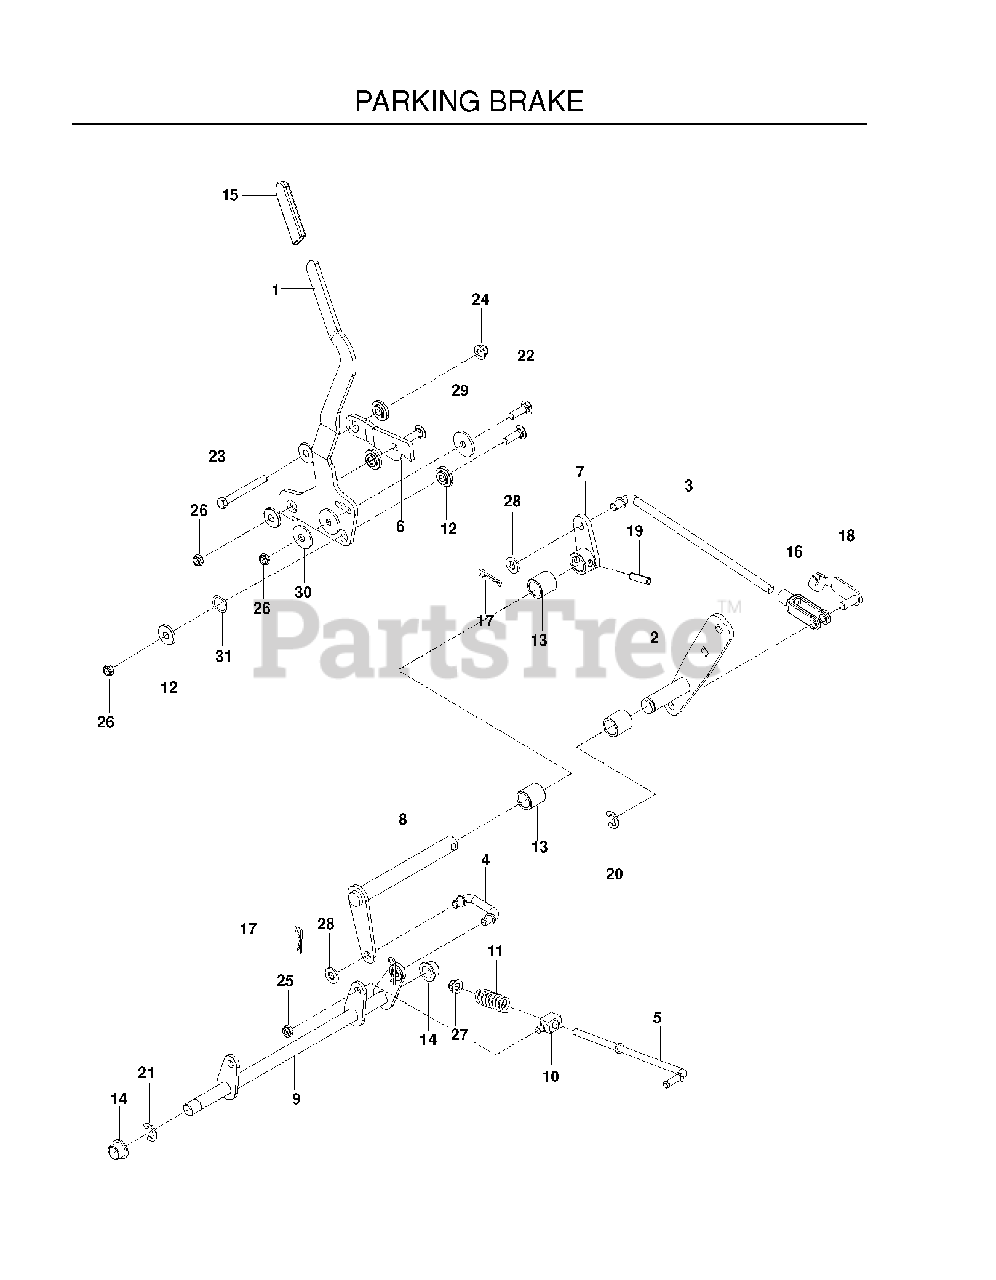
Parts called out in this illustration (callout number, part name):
1	LEVER, BRAKE, BLK
6	LINK, FOLLOWER
7	ARM, RT BRAKE
10	SWIVEL, BRAKE
12	BUSHING, BRAKE
13	BUSHING, SLEEVE 3/4 X 1.0
17	HAIRPIN #2
18	PIN, CLEVIS SPRING, 3/8
19	5/16 DIA ROLL PIN
20	E RING 3/4
21	5/8 E-RING
22	RHSNB 3/8-16 X 1-1/4
23	HCS 3/8-16 X 3-1/4 GR5 ZD
24	NUT 3/8-16 HEX FLG NYLOC ZD
25	5/16-18 THIN PROF NY
26	NUT HEX 3/8-16 NYLON, THIN
27	5/16-18 NYLOC FLANGE NUT
28	WASHER 3/8 SAE FLAT
29	WASHER, FRICTION, 1/8
30	CONE WASHER
31	WASHER, .825 X 1.087, WAVE
